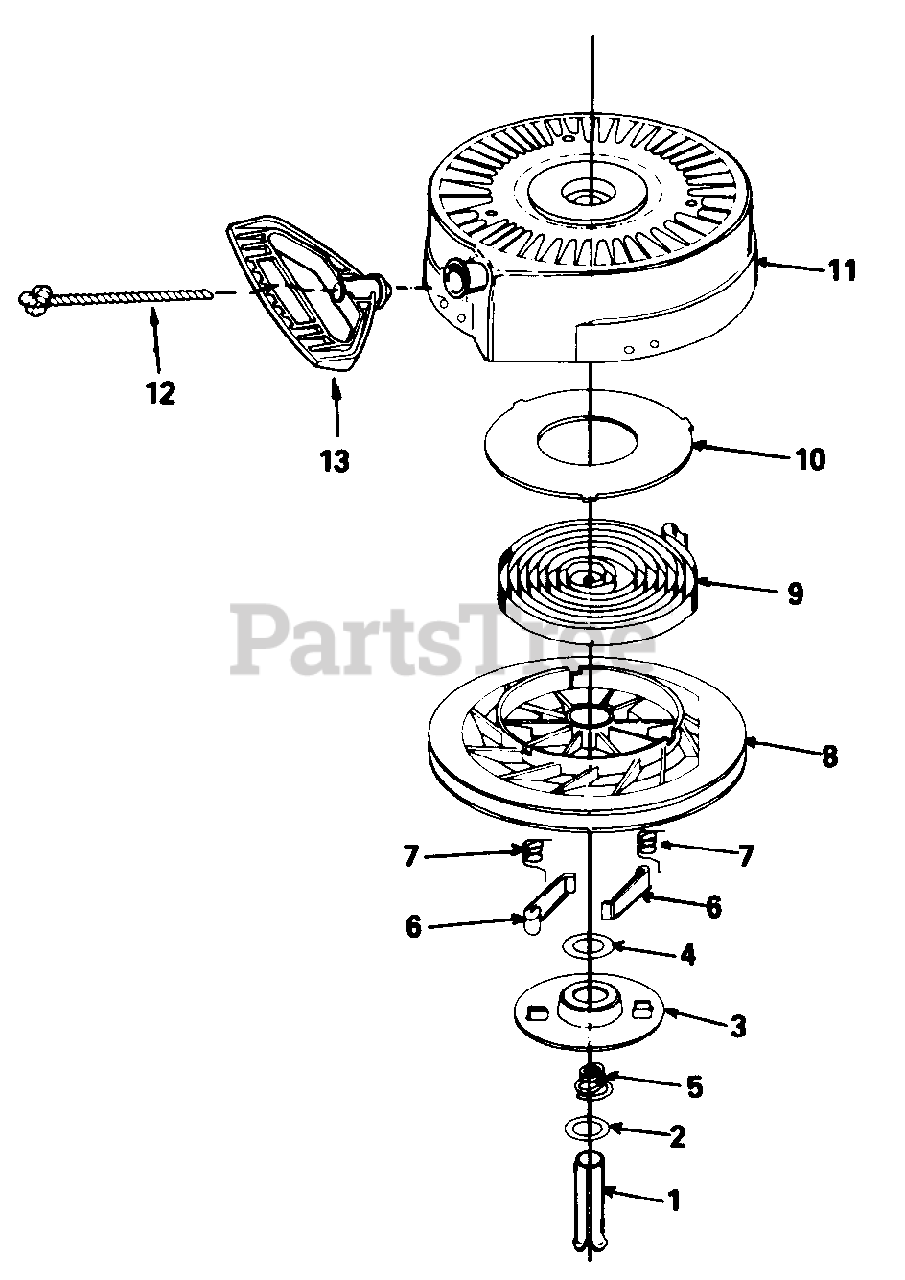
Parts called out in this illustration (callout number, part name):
1	Pin, Spring
5	Spring, Brake
6	Dog, Starter
7	Spring, Dog
8	Pulley
9	Spring, Rewind
10	Cover, Spring
11	Housing Ass'y., Starter
12	Rope, Starter
13	Handle, Mitten Grip
